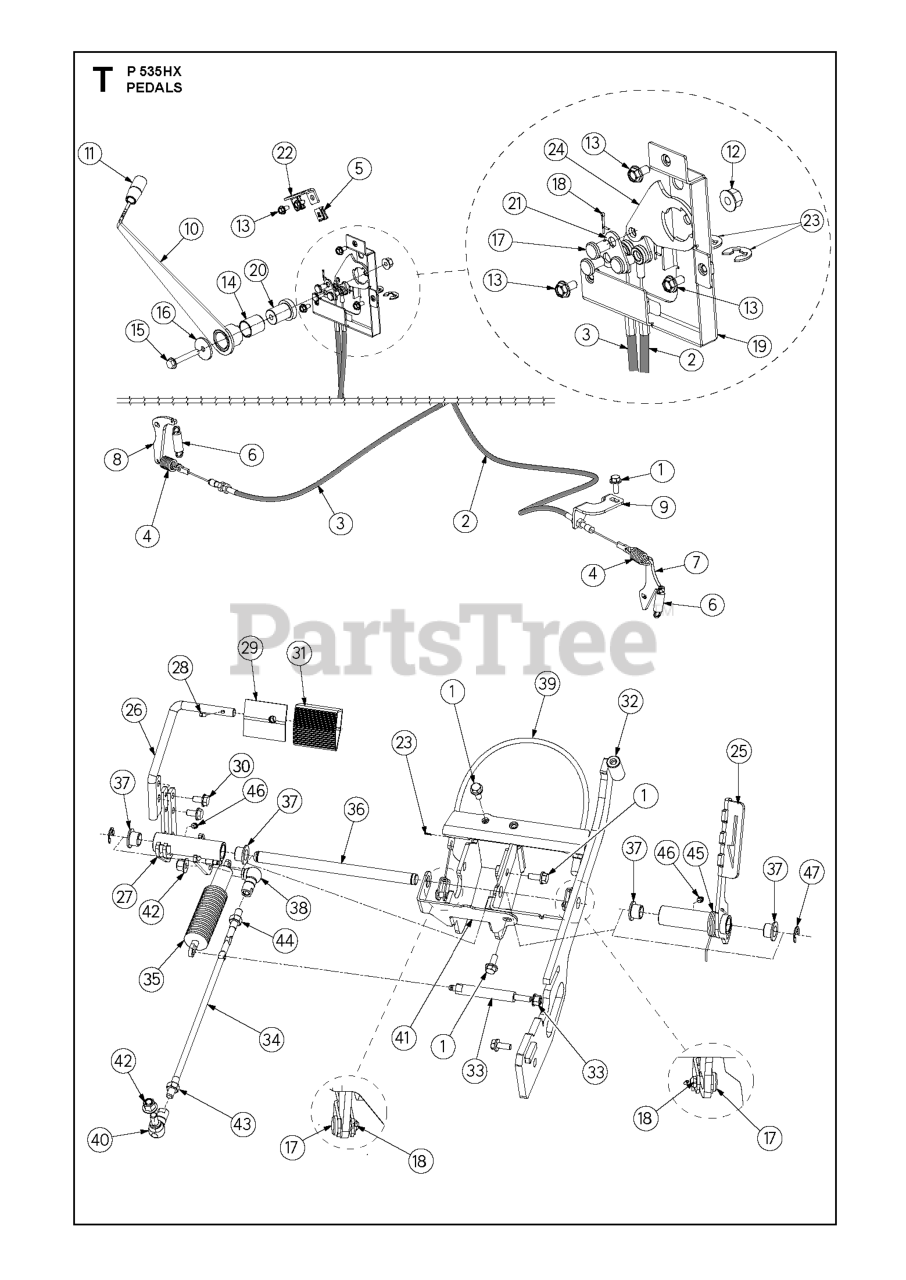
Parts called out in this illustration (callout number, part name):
6	DRAW SPRING L=50
12	NUT FLANGE
13	SCREW EHHFM
17	Clevis Pin
18	Cotter Pin
31	PEDAL RUBBER
35	SHOCK ABSORBER
37	BUSHING
46	GREASE NIPPLE
